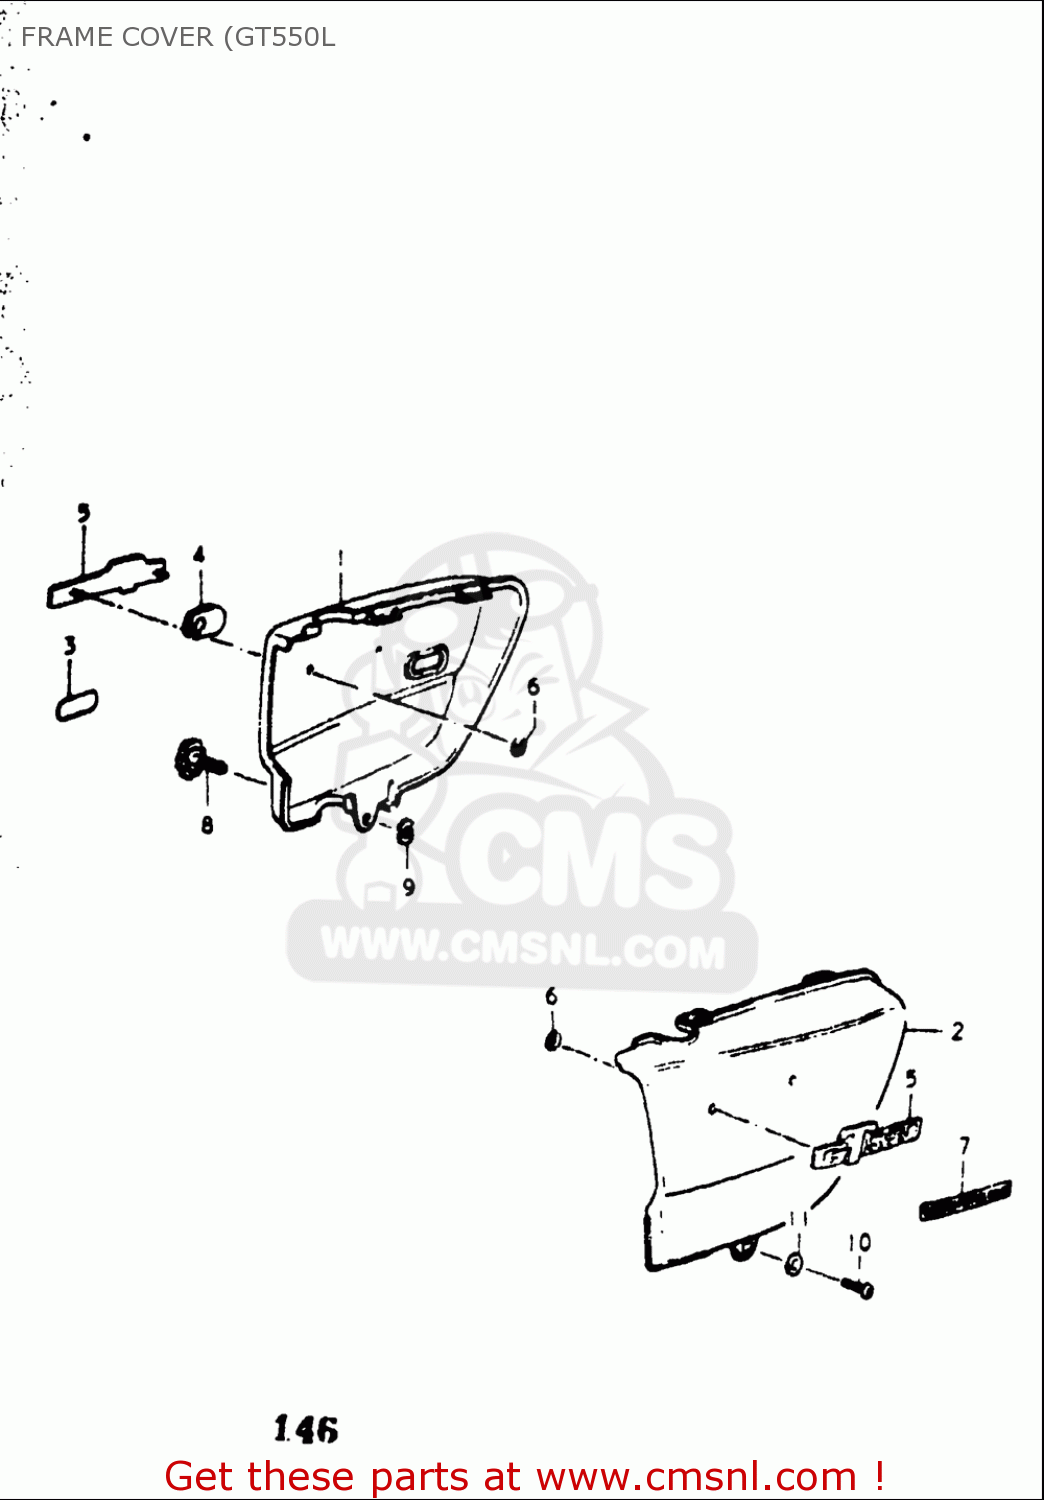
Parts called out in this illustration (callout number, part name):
1	COVER,FRAME,R
2	COVER,FRAME,L
3	EMBLEM,CCIS
5	EMBLEM,FRAME COVER,R
6	NUT
8	KNOB,FRAME COVER,R
9	NUT
11	WASHER(6.5X20X1.2)
